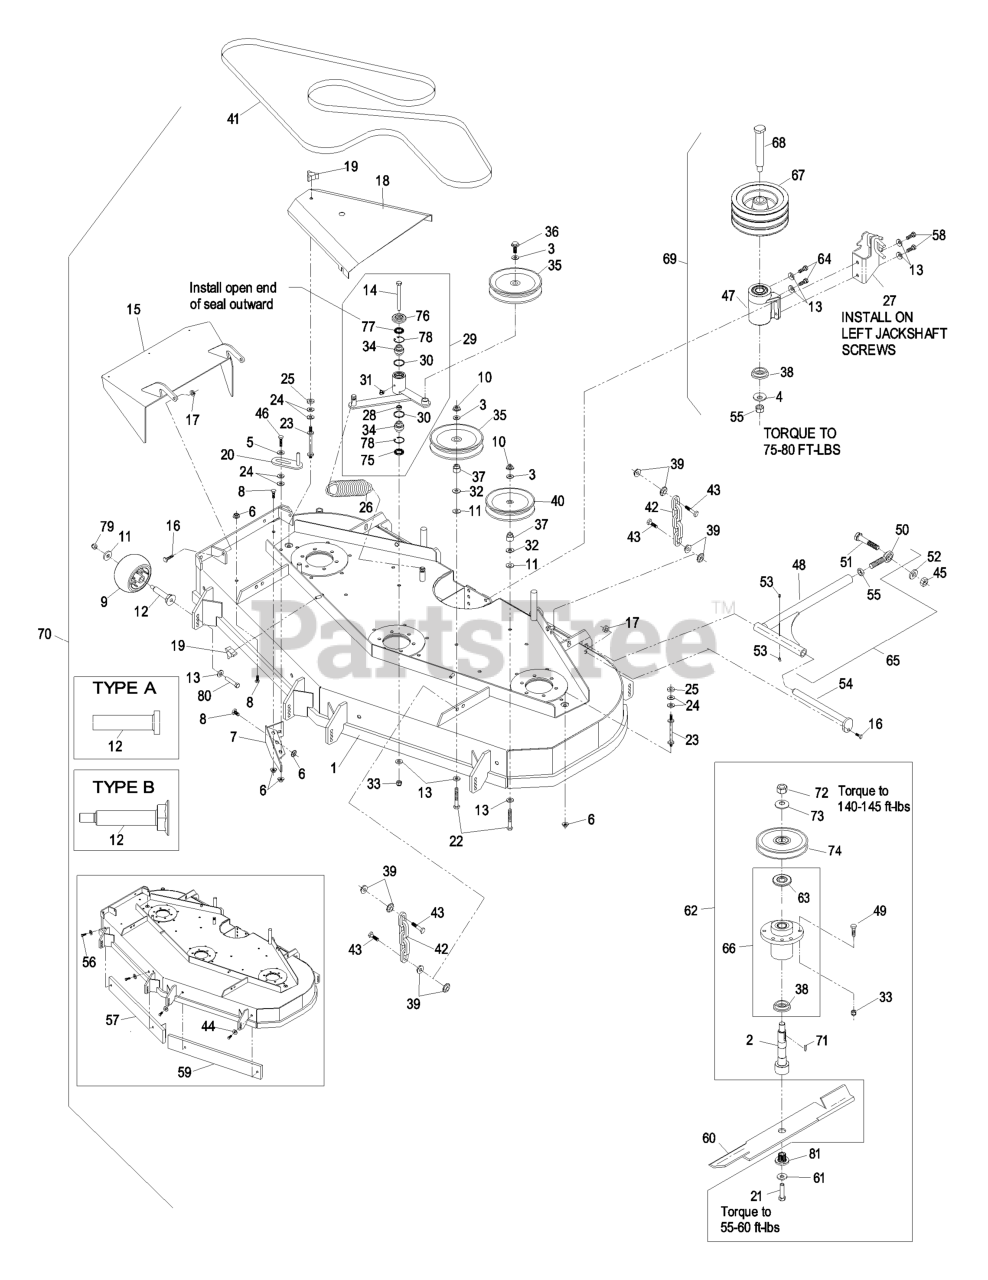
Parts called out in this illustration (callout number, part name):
1	ASM,DECK W/DECALS XP604
2	KIT, SPLINED SPINDLE 103-
3	WASHER-FLAT
4	WASHER-SPRING
5	WASHER-SPRING
7	WLD,BAFFLE DISCHARGE
8	SCREW-HH
9	ROLLER-SCALP, ANTI
10	NUT-HHF, WHIZ
12	BUSHING-ROLLER
13	WASHER-BELLEVILLE
14	SCREW-HH
15	WLD,CHUTE XP604
16	SCREW-HH
17	NUT-LOCK, NI
18	SHIELD,BELT
19	KNOB-3 PRONG
20	GUIDE-BELT
21	SCREW-HH
22	SCREW-HH
23	STUD-SHIELD, BELT (SHORT)
24	WASHER-FLAT
29	KIT,DECK IDLER LZ/XP
31	FITTING-GREASE, 90 DEG
32	WASHER-FLAT
33	NUT-LOCK, NI
34	BEARING-SPHERICAL
36	SCREW-HHF
37	BUSHING-IDLER
38	SPACER-GUARD, BOTTOM
40	PULLEY-IDLER
41	BELT,BLADE DRIVE
42	CHAIN-LIFT, DECK
43	SCREW-HH
44	WASHER-SPRING
45	NUT-HEX
46	SCREW-HH
49	SCREW-HH
50	BALLJOINT-SPHERICAL
51	SCREW-HH
52	WASHER-LOCK
53	FITTING-GREASE
54	PIN-STRUT
55	NUT-HEX
56	SCREW-HH
57	WEIGHT BAR ASM
58	SCREW-HH
61	WASHER-SPRING
62	ASM, CUTTER HSG COMPLETE
63	GUARD-BEARING, TOP
64	SCREW-HH
65	STRUT ASM
66	KIT, CUTTER HOUSING
67	SHEAVE-JACKSHAFT
68	JACKSHAFT
69	ASM,JACKSHAFT
70	Complete Deck Assy
72	NUT-HH
74	SHEAVE,BLADE DRIVE 6.30
75	SEAL-LIP, DOUBLE
76	GUARD-TOP
77	SEAL-LIP, SINGLE
78	RING-SNAP
79	NUT-HHF, WHIZ
80	SCREW-HH
81	BUSHING,SPLINED
